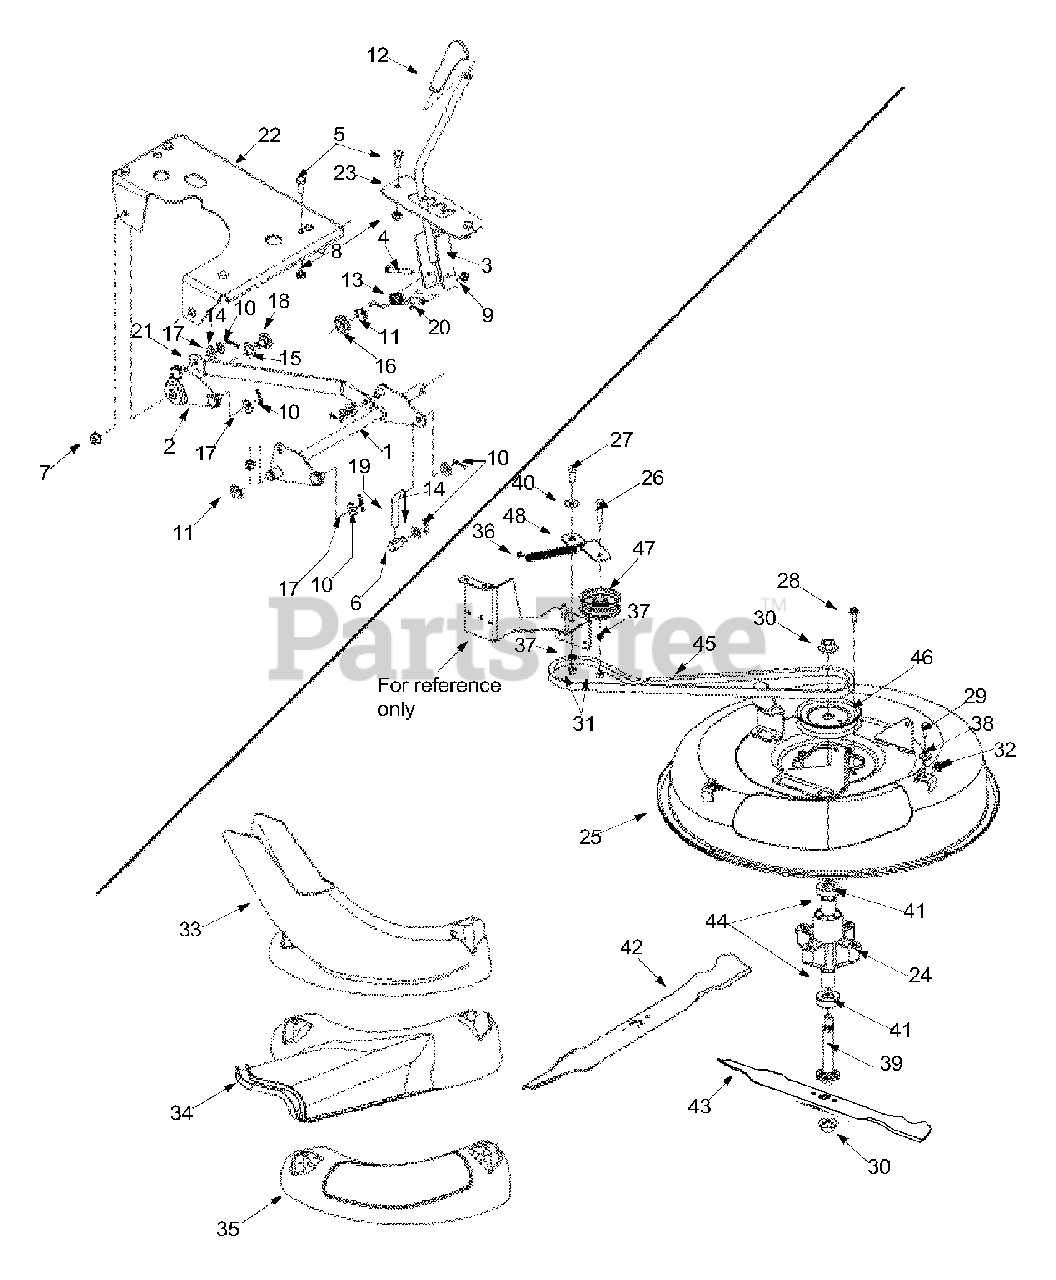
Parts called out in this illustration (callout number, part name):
1	Shift Assembly: Front Lift
2	Pivot Bracket Assembly
3	Bracket Assembly: Lift Handle
4	Hex Bolt 1/4-20 x 2.25
5	Hex Bolt M8-1.25: 20
6	Ferrule
7	Flange Lock Nut 3/8-16
8	Hex Lock Nut M8-1.25
9	Lock Nut 1/4-20
10	Hairpin Clip
11	E-Ring
12	Handle Grip
13	Torsion Spring
14	Thrust Washer .375 x .70 x .030
15	Flat Washer 5/8 x 1.0 x .030
16	Flange Washer .633 x .883
17	Flat Washer .407 x .812 x .135
18	Shoulder Screw .625 x .17: 3/8-16
19	Lift Link
20	Spacer
21	Upper Lift Link Bracket
22	Lift Hanger Bracket
23	Lift Indx. Bracket
24	Spindle Housing
26	Hex Screw 3/8-16 x 1.75
27	Hex Bolt 3/8-16 x 1.0
28	TT Screw 5/16-18 x 0.875
30	Flange Nut 5/8-18
31	Hex Nut 3/8-16
32	Speed Nut
33	Grass Catcher Chute
34	Side-Discharge Chute
35	Mulch Plug
36	Extension Spring
37	Lock Washer
38	Flat Washer 8.4 x 24
39	Spindle Shaft
40	Shoulder Spacer
41	Ball Bearing
42	Blade: Bagging
43	Blade: 3-in-1
44	Spacer
45	Belt: V Type
46	Deck Pulley
47	Flat Idler Pulley
48	Idler Bracket: Deck
